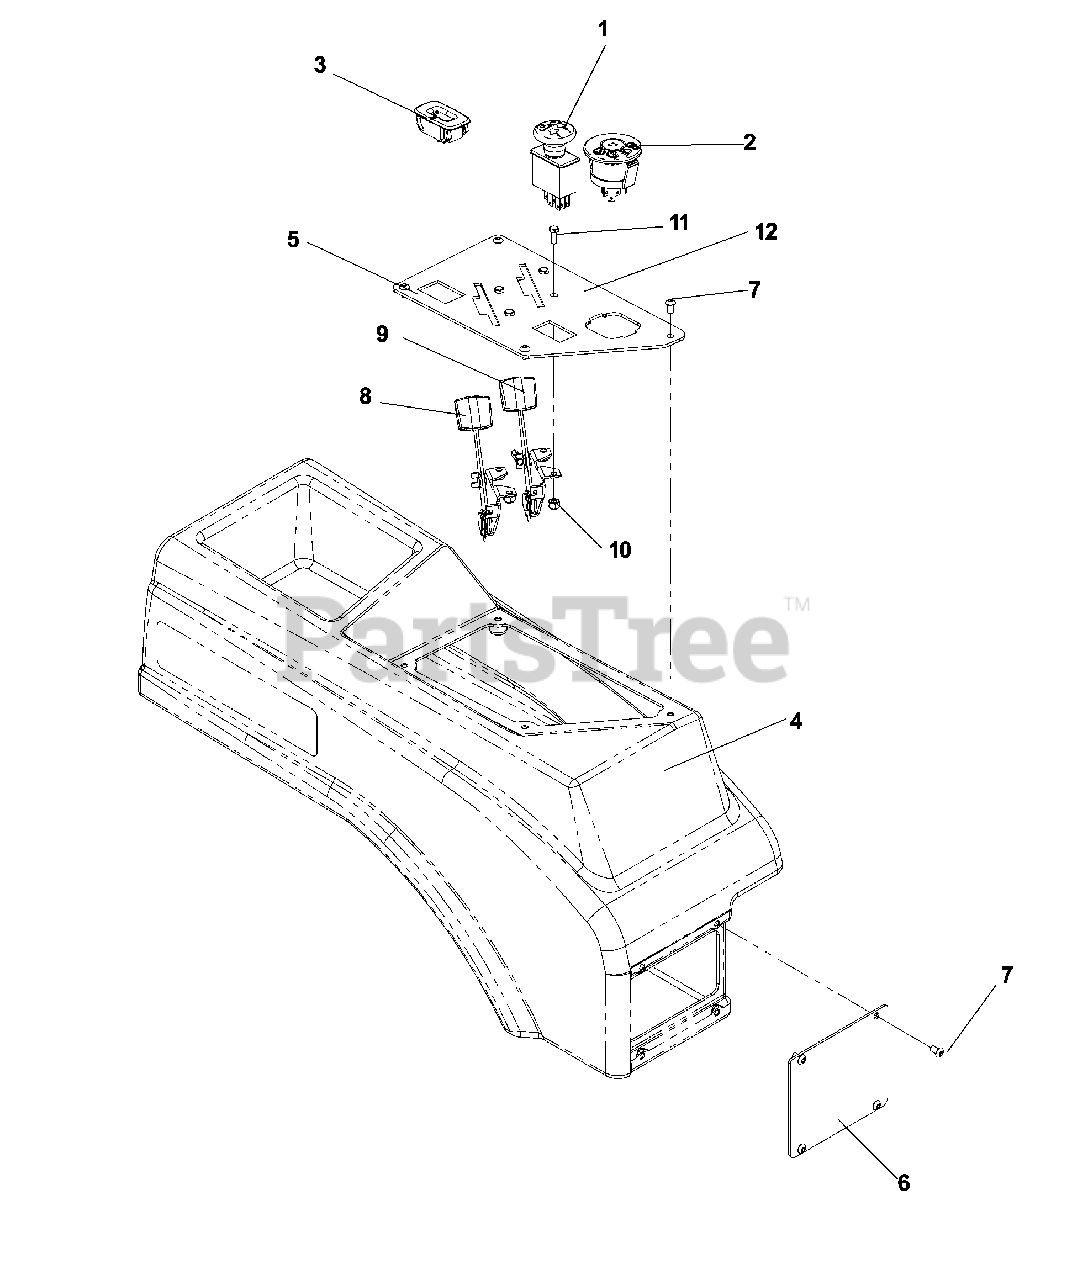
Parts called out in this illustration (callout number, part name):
1	SWITCH, BLADE
2	IGNITION SWITCH
3	HOUR METER
4	TANK, CONSOLE, RT
5	CONTROL PANEL
6	PANEL, LIGHT DELETE
7	SCR #10-24 X 3/8 SKT HD BLK OX
8	CABLE THROTTLE
9	CABLE CHOKE
10	NUT 10-24 NYLOC
11	HCS #10-24 X 1/2
12	DECAL, CONTROL
